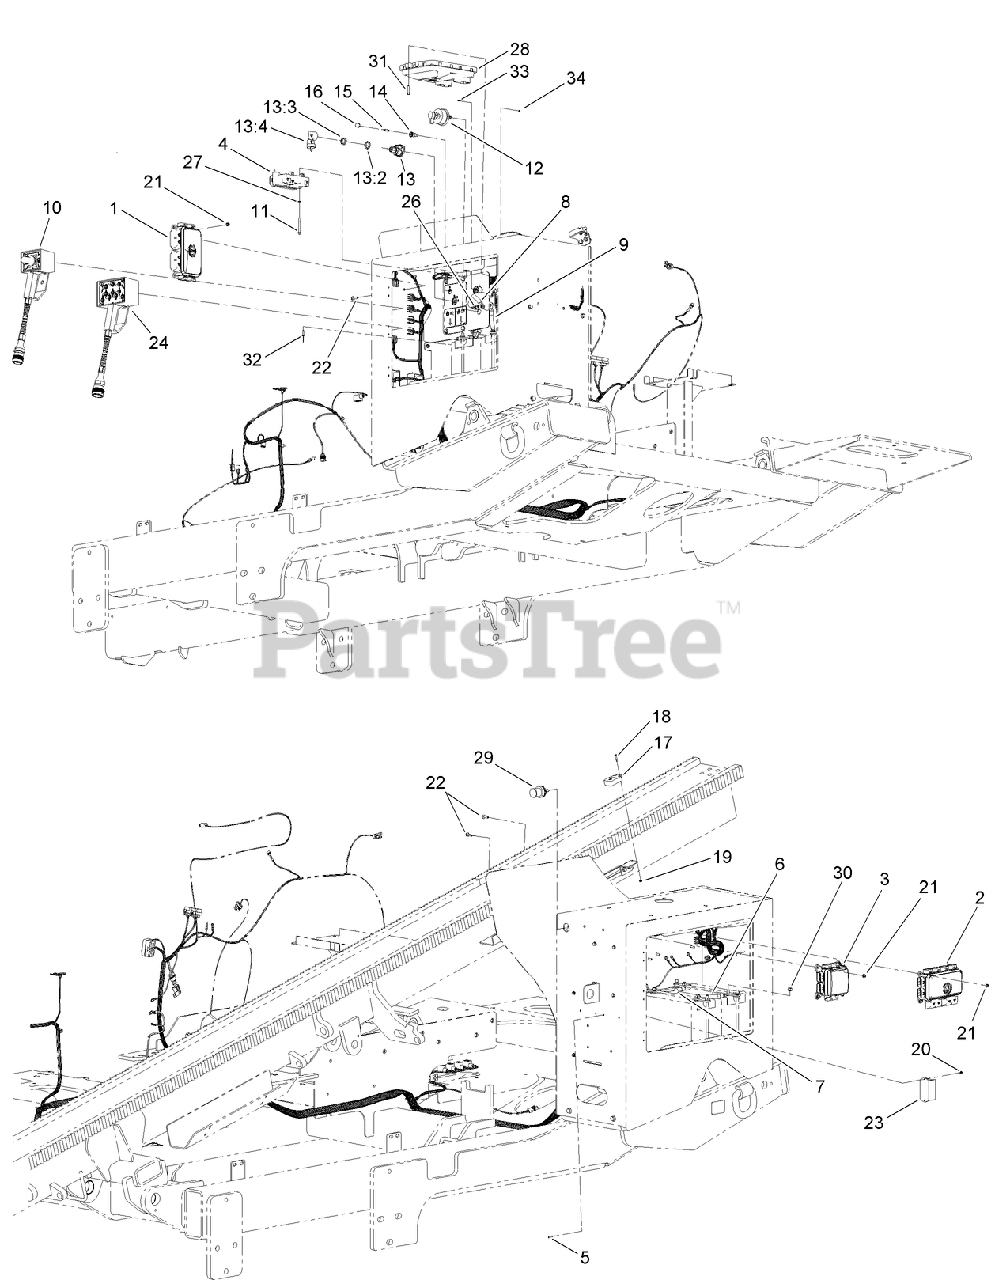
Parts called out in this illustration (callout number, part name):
1	BOX-VEC, MAIN (A)
2	BOX-VEC, MAIN (B)
3	BOX-VEC, MAIN (C)
4	COMPUTER-EXPANDER, OUTPUT
5	SCREW-PPH
6	CABLE-BATTERY, POSITIVE
7	CABLE-BATTERY, NEGATIVE
8	CABLE-BATTERY, POSITIVE
9	CABLE-BATTERY, POSITIVE
10	TRAVEL PENDANT ASM
11	SCREW-FLANGE, METRIC
12	SWITCH-DISCONNECT, MASTER
13	IGNITION SWITCH ASM
13:2	NUT-HEX
13:3	NUT-FACE
13:4	IGNITION KEY SET
14	TYPE T-2 SOCKET ASM
15	LAMP-LED
16	LENS-DOME, FLUTED AMBER (TYPE T2)
17	SWITCH-PROXIMITY
18	SCREW-PPH
19	NUT-KEPS
20	NUT-LOCK
21	NUT-FLANGE, NI
22	SCREW-HHF
23	CONNECTOR-PACK, RESISTOR
24	LIFE JACKET ASM
26	HARNESS-WIRE, FUSIBLE LINK
27	WASHER-FLAT
28	CONTROLLER ASM (88 PIN, UNPROGRAMMED)
29	POST-BATTERY, REMOTE
30	NUT-KEPS
31	SCREW-HHF
32	RIVET-POP
33	SCREW-PRH, SLOTTED
34	NUT-LOCK, NI
